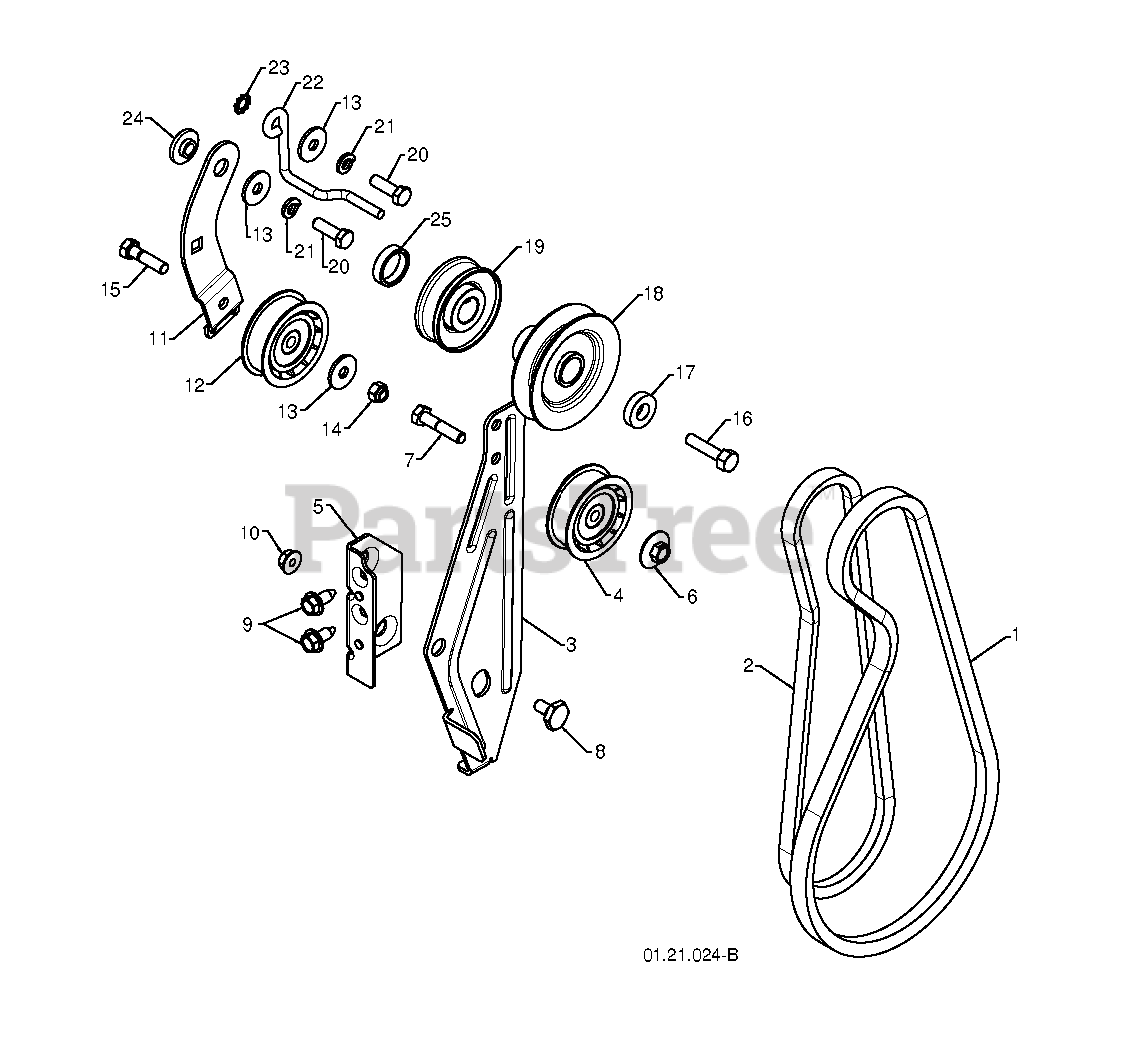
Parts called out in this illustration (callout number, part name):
1	VBELT; IMPELLER_39.09
2	TRACTION BELT
3	ARM.IDLER.BRAKE
4	PULLEY.IDLER.W/SPACER.
5	RP BRACKET.IDLER
6	NUT.FLANGE.HEX.5/16X18.BLACK
7	HEX BOLT
8	BOLT.SHOULDER.1/2X12
9	NUT.LOCK.5/16-18
10	BOLT.HEX.HD.WASHER.5/16-18X.75
11	ARM, IDLER
12	PULLEY.W/SPACER.2.25
13	STEEL WASHER
14	NUT.71038.31-18.HEX.NYLOCK
15	BOLT.5/16-18X1-1/4 FULL.THREAD
16	SCREW, HEX HD 3/8-24 X 1-3/8
17	WASHER, FLAT 3/8
18	PULLEY.ENG.IMPELLER.SNOW
19	PULLEY,ENGINE TRACTION DRIVE
21	WASHER.LOCK.HVY.HLCL.SPR.5/16
22	GUIDE.BELT.HYDRO.H
23	WASHER EXT TOOTH LOCK 5/16
24	RP BUSHING, IDLER PIVOT
25	SPACER.ENGINE.PULLEY
